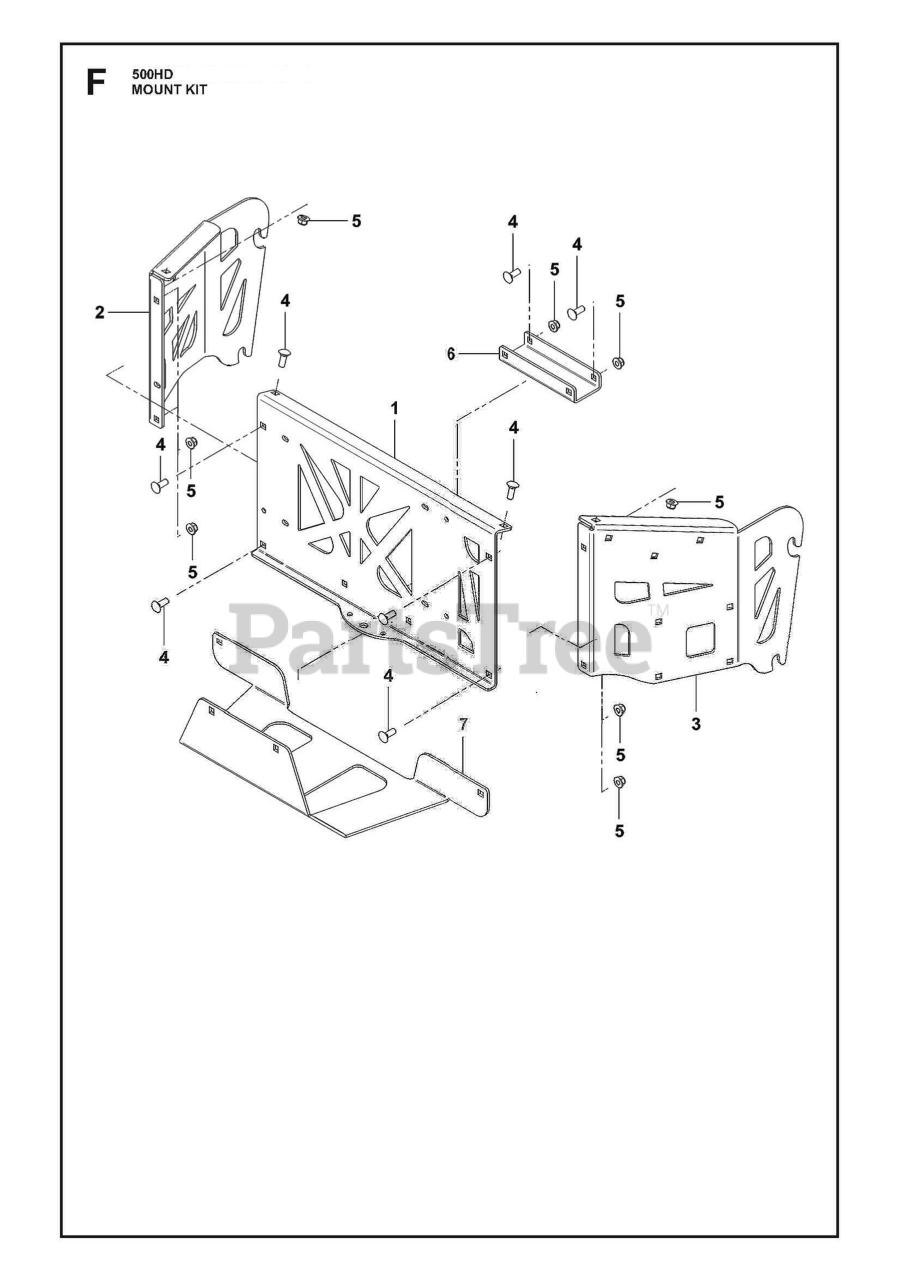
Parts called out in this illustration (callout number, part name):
1	BRACKETS
2	BRACKETS
3	BRACKETS
4	Bolts
5	GSPW Nuts
6	SPACERS
7	GUARDS
